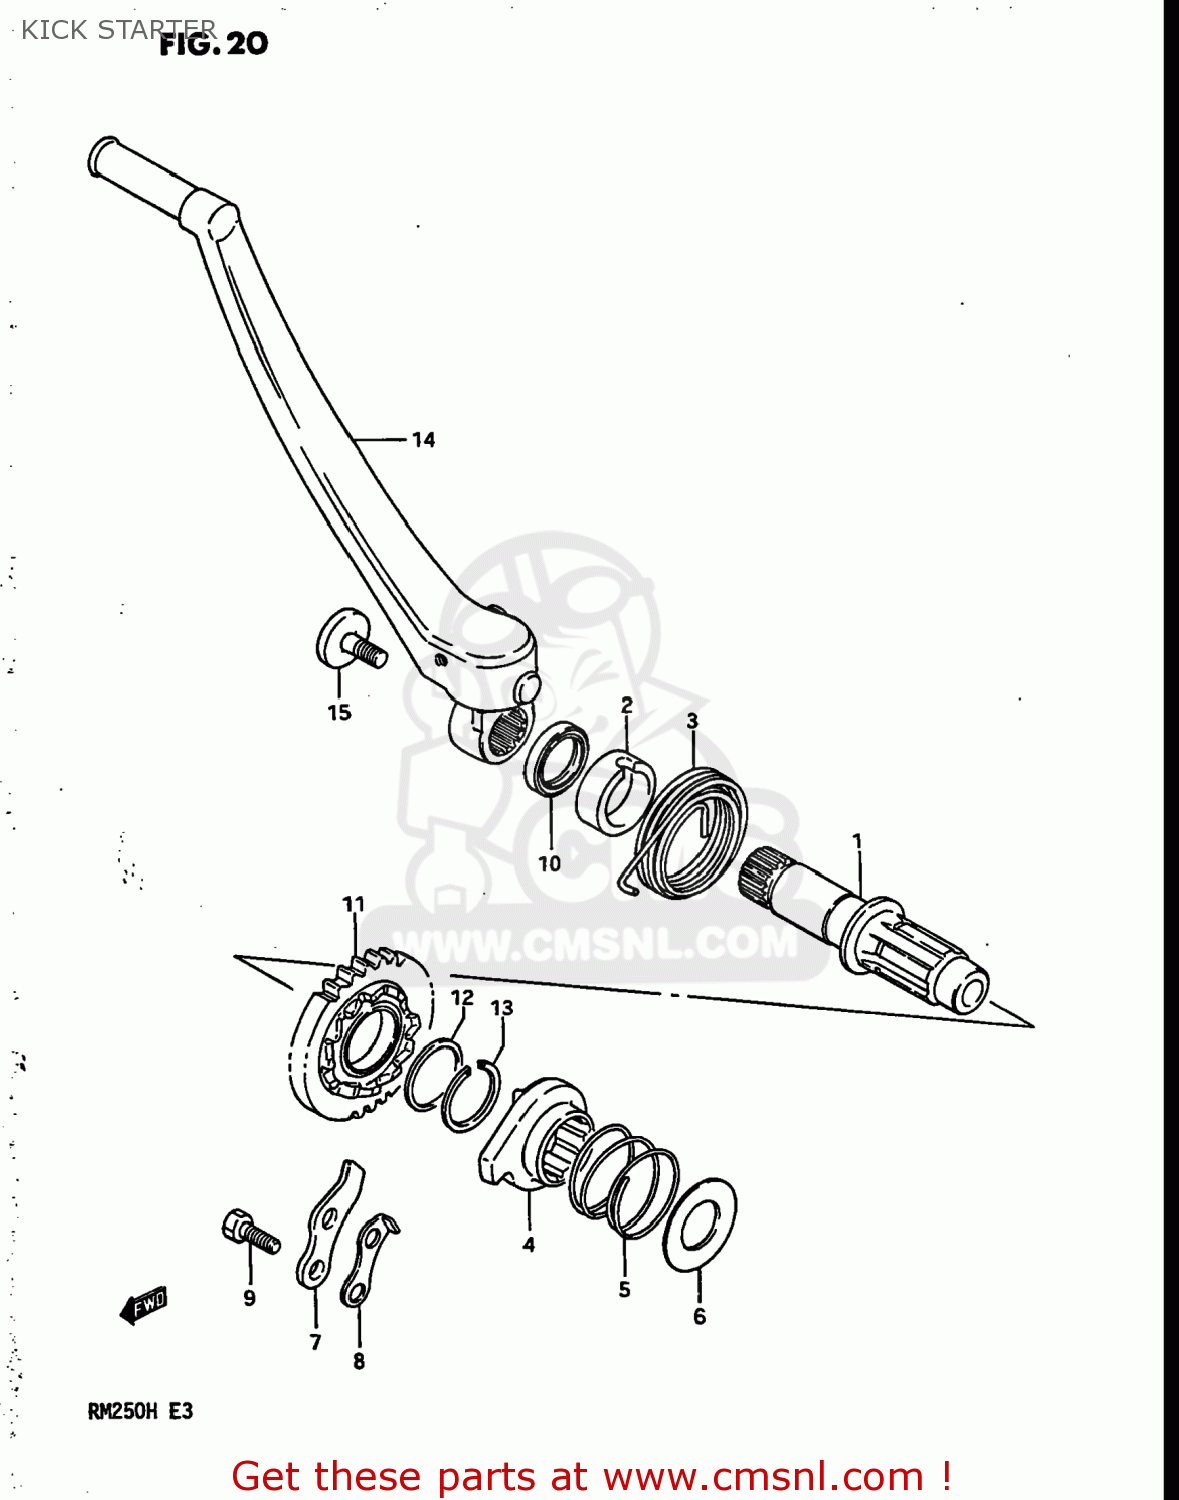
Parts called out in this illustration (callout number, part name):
1	SHAFT,KICK STARTER
2	GUIDE,KICK STARTER SHAFT
3	SPRING
4	STARTER,KICK
5	SPRING
6	WASHER
7	GUIDE,KICK STARTER
8	STOPPER,KICK STARTER
9	BOLT
10	SEAL,OIL(20X27X5)
11	GEAR
12	SHIM
13	CIRCLIP
14	LEVER ASSEMBLY,KICK STARTER
15	BOLT
